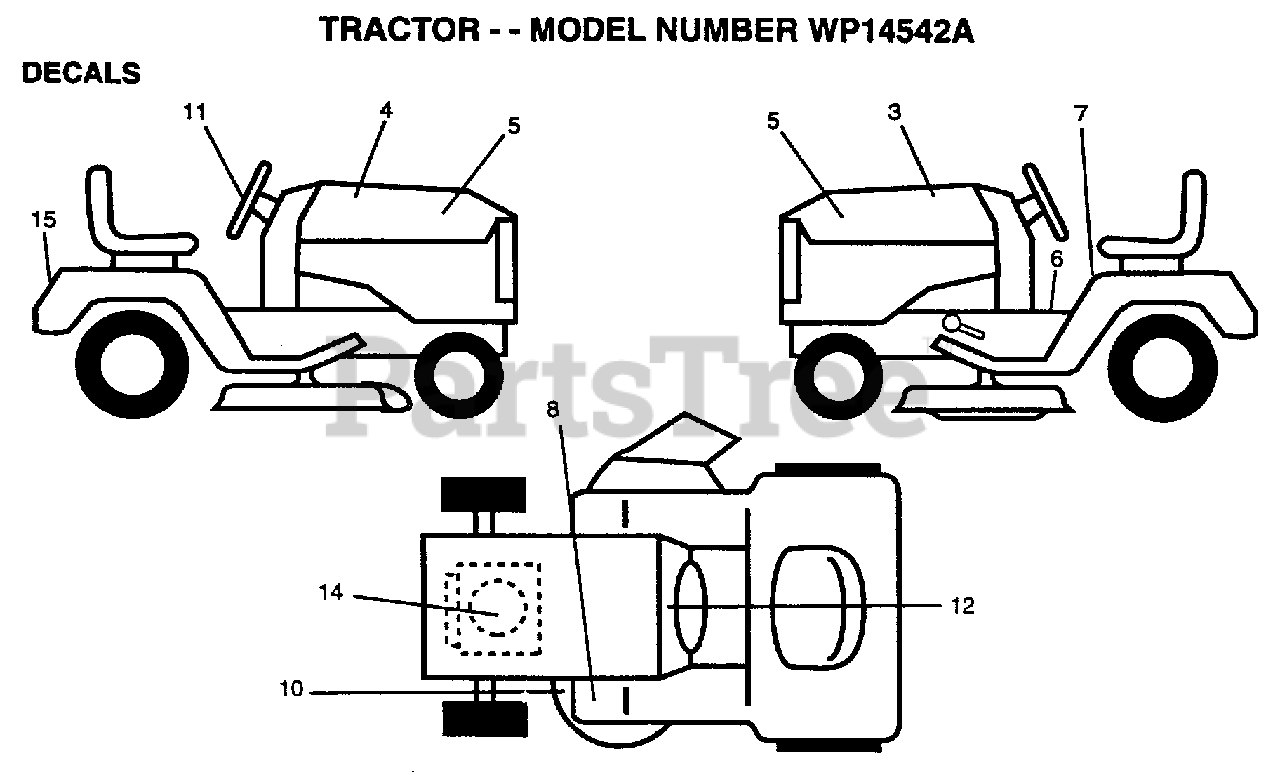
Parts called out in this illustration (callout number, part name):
3	DECAL.HOOD.LH
4	DECAL.HOOD.RH
5	DECAL.INS.HD.LT.
6	DECAL BRAK PARK
7	DECAL
10	DECAL
11	DECAL, INSERT
12	DECAL.DASH.INST.
14	DECAL, ENGINE
15	DECAL, FENDER LOGO
